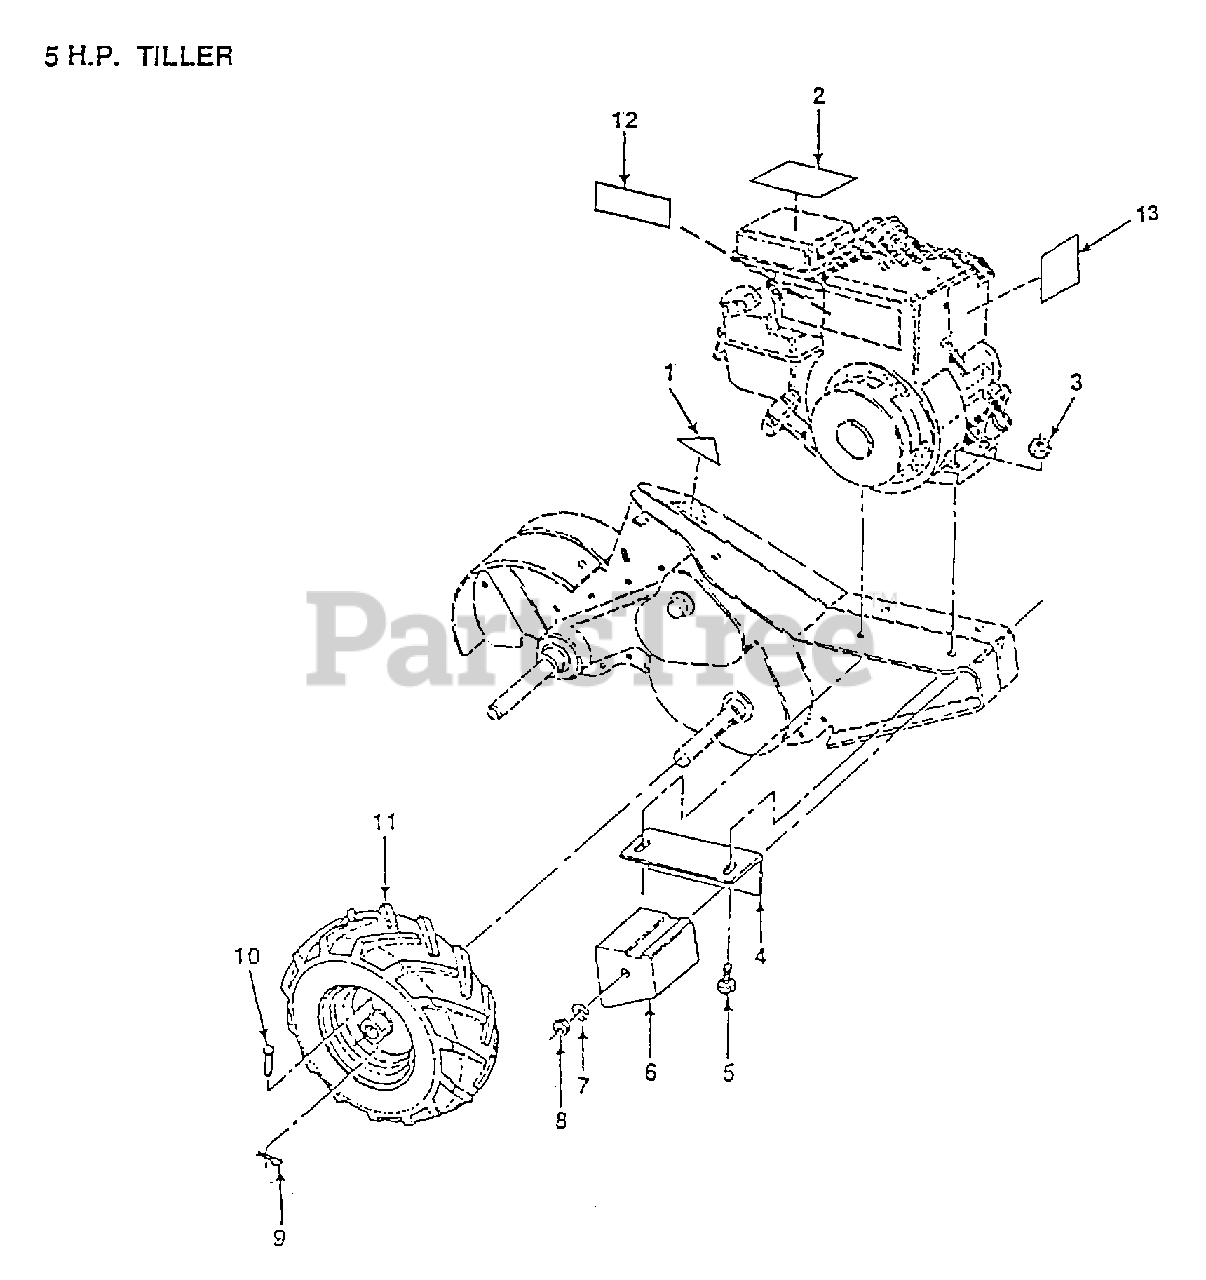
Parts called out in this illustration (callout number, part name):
2	DECAL TI
4	BRACKET RH CRT
5	BOLT.HEX.5/16-1.5
6	COUNTERWEIGHT CRT
7	LOCKWASHER
8	NUT.HEX.3/8-16UNC
9	RETAINER M
11	TIRE.CHV.13X5.0-6
11	RIM
